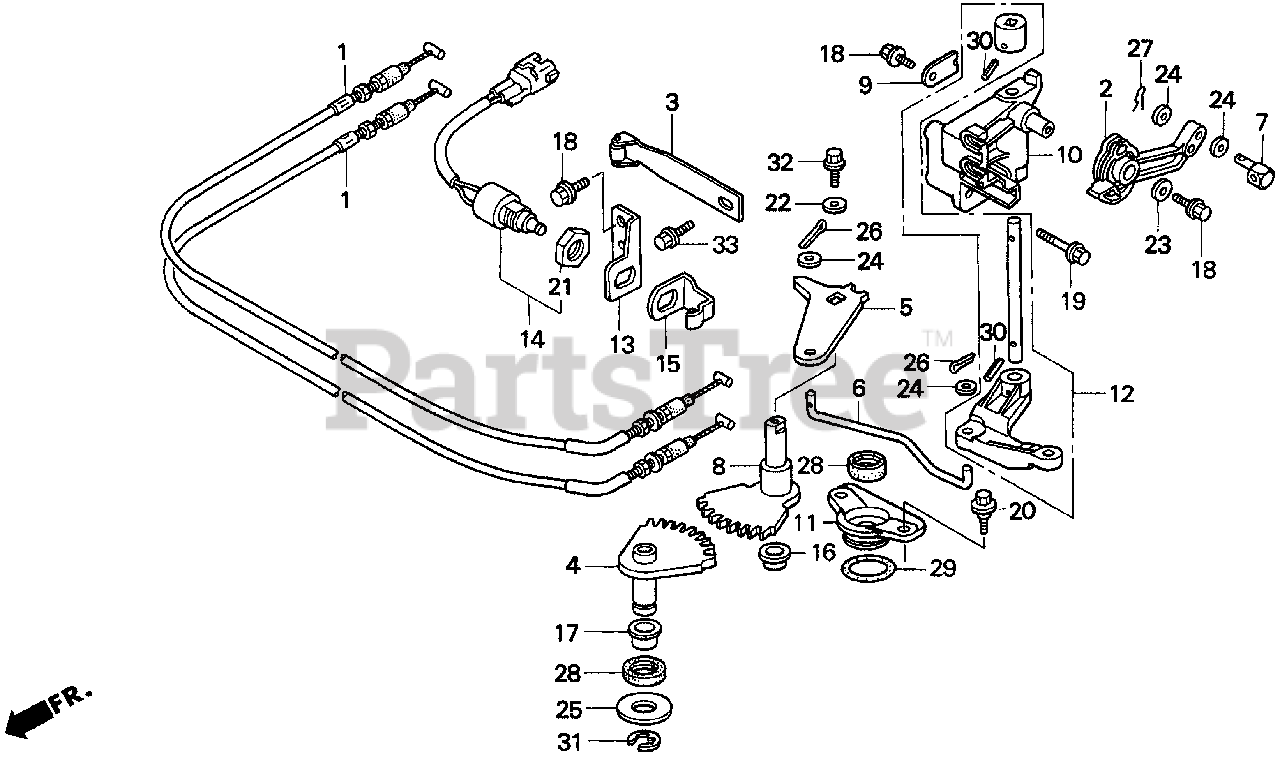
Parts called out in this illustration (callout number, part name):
1	CABLE, THROTTLE
2	ARM, THROTTLE
3	SPRING, CLICK
4	SHAFT, SHIFT (A)
5	ARM, SHIFT
6	ROD, LINK
7	PIVOT, SHIFT
8	SHAFT, SHIFT (B)
9	PLATE, SHIFT SHAFT
10	BRACKET, SHIFT LINK *NH8* (DARK GRAY)
11	HOLDER, SEAL
12	LINK, SHIFT
13	BRACKET, NEUTRAL SWITCH
14	SWITCH ASSY., NEUTRAL
15	PLATE, NEUTRAL SWITCH
16	BUSH, TORQUE LINK
17	BUSH (14X10)
18	BOLT, FLANGE (6X12)
19	BOLT, FLANGE (6X35)
20	BOLT, FLANGE (6MM)
21	NUT, HEX. (20MM)
22	WASHER (6MM)
23	WASHER (6MM)
24	WASHER, PLAIN (6MM)
26	PIN, SPLIT (2.0)
27	PIN, SPECIAL LOCK (6MM)
28	SEAL, WATER (14X26X6)
29	O-RING (27X2.0)
30	PIN, SPRING (3X18)
31	E-RING (12MM)
32	BOLT, FLANGE (6X12)
33	BOLT, FLANGE (6X12)
